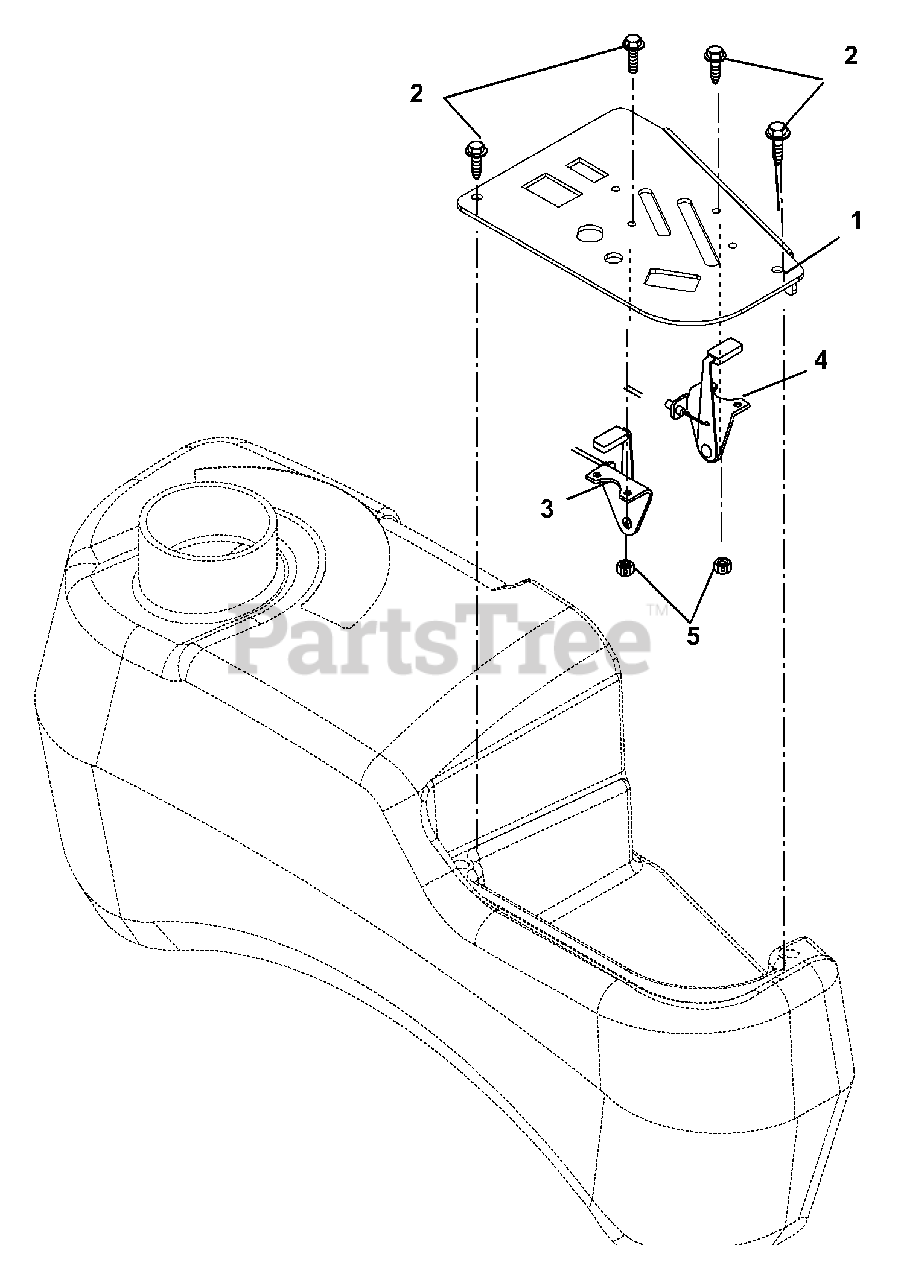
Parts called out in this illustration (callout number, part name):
1	Panel, Control
2	Screw, Machine 10-24 x .50 Hex Washer Head
3	Cable, Throttle
4	Cable, Kohler Choke
5	Nut, Locking Nylon 10-24 With Insert
